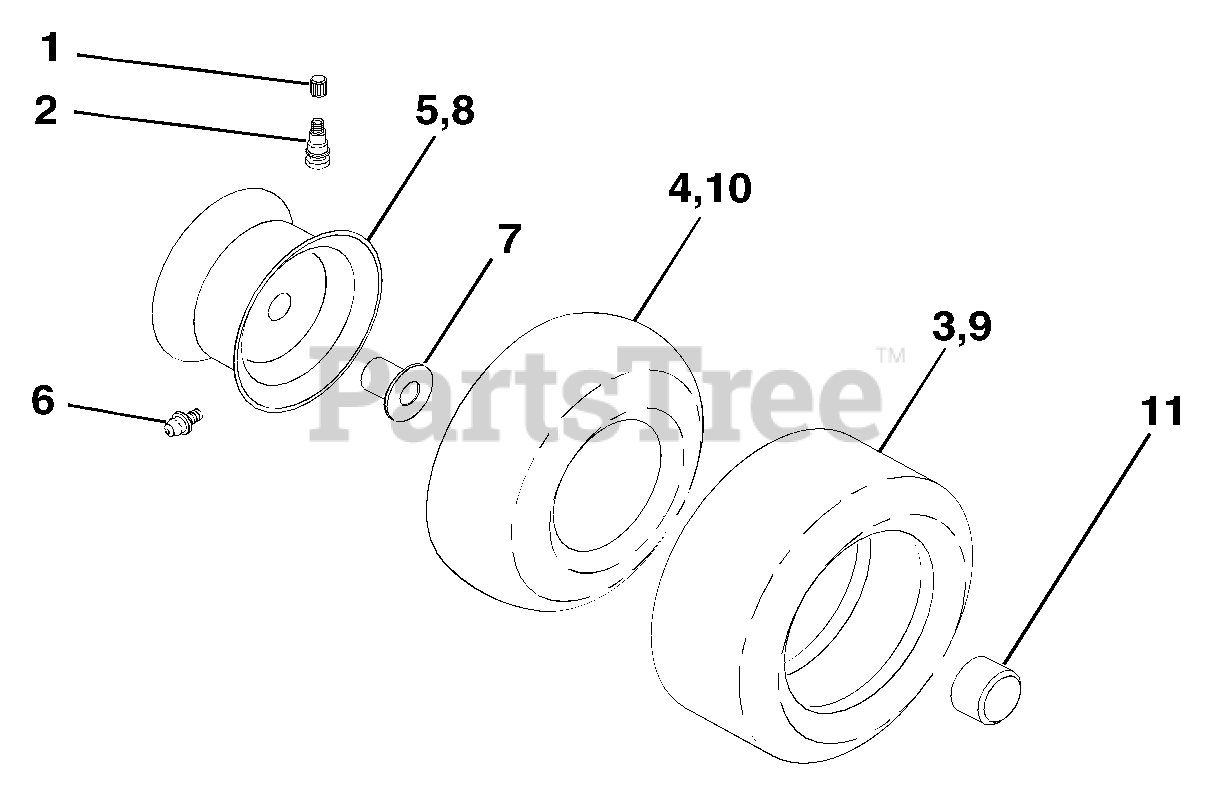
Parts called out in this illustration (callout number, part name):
1	Cap Valve Tire
2	Stem Valve
3	Tire F Ts 15 X 6 0 - 6 Service
4	Tube Front (Service Item Only)
5	Rim Asm 6"front Service
6	Fitting Grease (Front Wheel Only)
7	Bearing Flange (Front Wheel Only)
8	Rim Asm 8"rear Service
9	Tire R Ts 20x10-8 C Service
10	Tube Rear (Service Item Only)
11	Cap Axle 1 50 X 1 00
